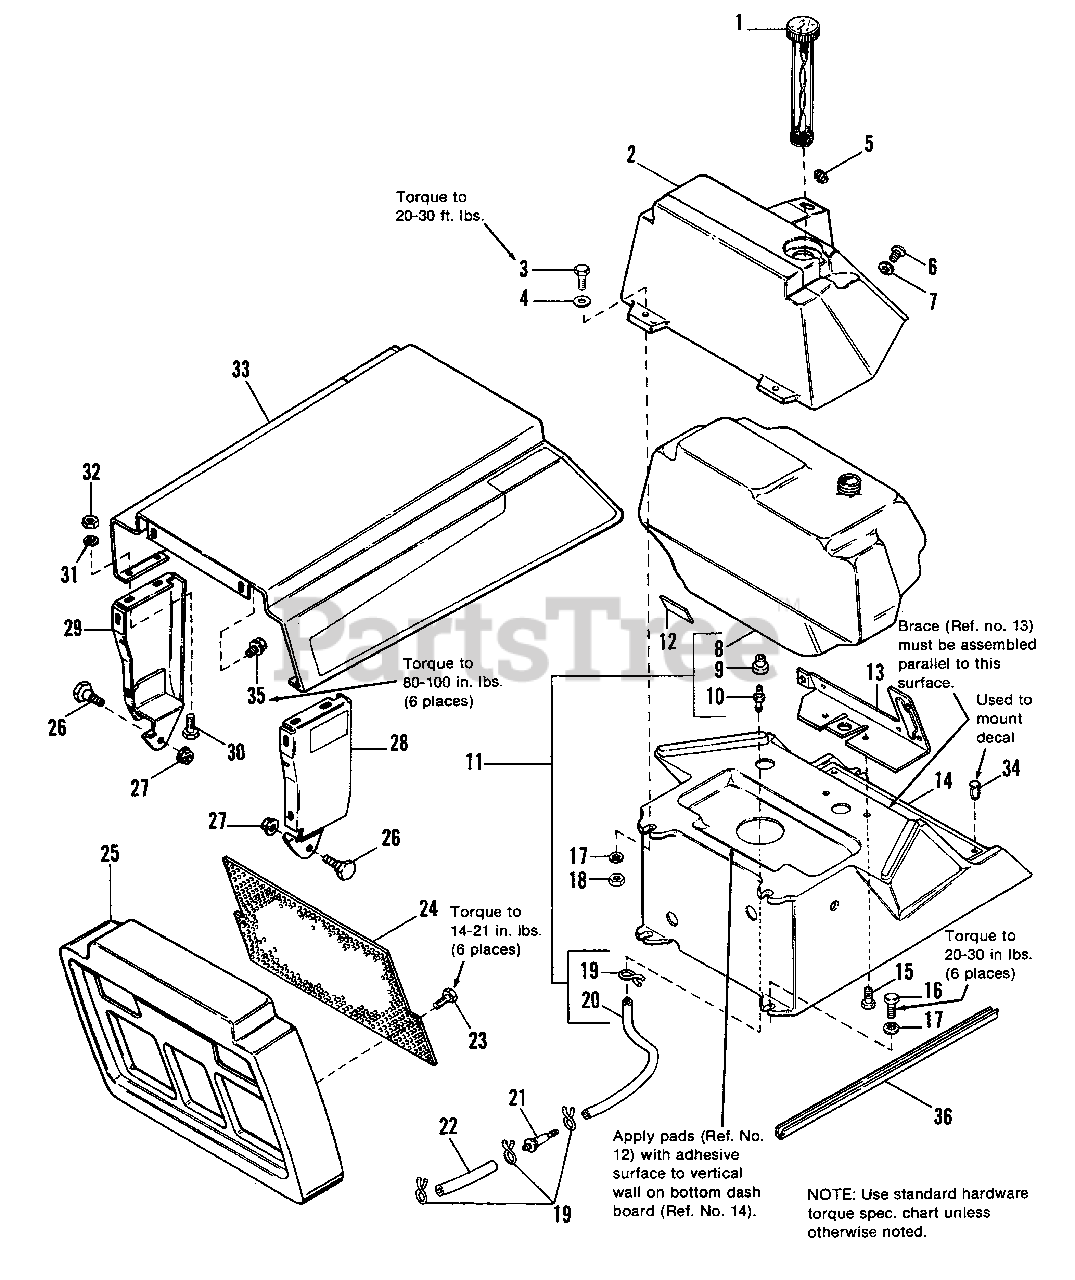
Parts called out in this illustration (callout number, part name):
2	DASHBOARD, Top
3	CAPSCREW, Hex, 1/4-20 x 1-1/4
4	WASHER, 1/4
5	CAP, Plug (Light Switch)
6	SCREW, Taptite Phillips, 1/4-20 x 3/4
7	WASHER, 3/16
11	TANK ASSY., Fuel
14	DASHBOARD, Bottom
15	SCREW, Taptite, 1/4-20 x 3/4
16	SCREW, Taptite, 1/4-20 x 1
17	LOCKWASHER, Dish, 1/4
18	LOCKNUT, Hex, 1/4-20
19	CLAMP, Hose
21	FILTER, Fuel
22	HOSE, Fuel
23	SCREW, Plastite, #10-14 x 1/2
26	BOLT, Shoulder, 5/16-18 x 7/8
27	LOCKNUT, Flange, Whiz, 5/16-18
28	PANEL ASSY., L.H.
29	PANEL ASSY., R.H.
30	CAPSCREW, Hex, 1/4-20 x 1/2
31	LOCKWASHER, 1/4
32	NUT, Hex, 1/4-20
34	CLIP, Canoe
35	SCREW, Plastite, 1/4 x 1
36	EDGING, Lower Dash
